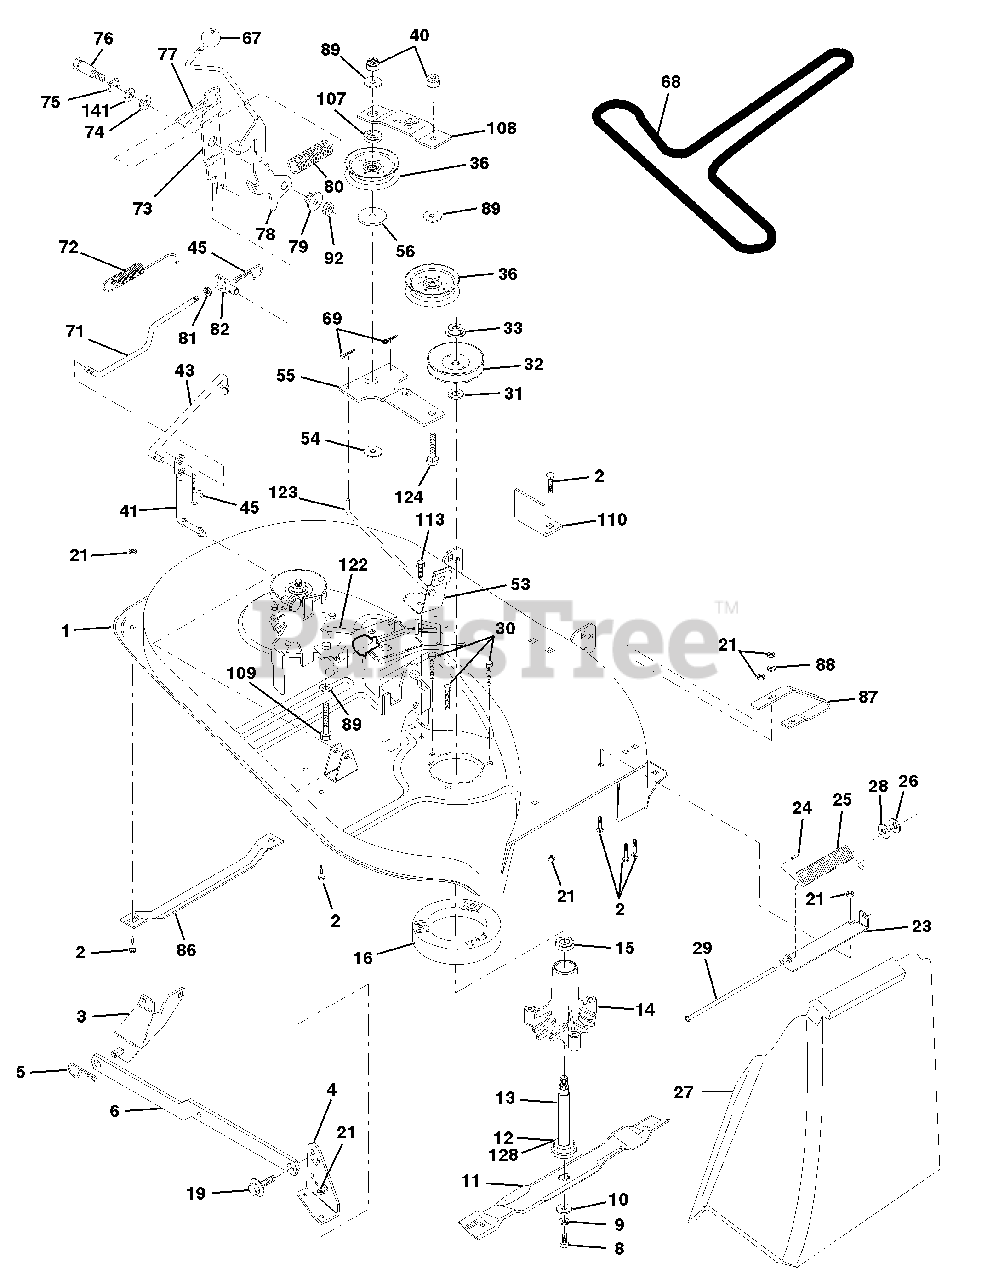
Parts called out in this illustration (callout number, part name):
1	Mower Housing
2	Bolt Rdhd Sqnk 5/16-18unc X3/4
3	Bracket assembly, front
4	Bracket assembly, decl
5	Retaining spring
6	Arm, suspension rear
8	Bolt 3/8-24x1 25 Gr8 Patched
9	Washer Lock Hvy 3/8 Unplated
10	Washer Hard Blade Mower Vented
11	Blade High Lift 38"
12	Bearing Ball #6204 (Mandrel)
13	Shaft Asm W/lower Bearing
14	Housing Mandrel Vented (machd)
15	Bearing Ball Mandrel
16	Stripper MWR
19	Bolt Shoulder
21	Nut Crownlock 5/16-18 UNC
23	Bracket Deflector Mower
24	Cap Sleeve 80 x 112 Blk Mower
25	Spring Deflector
26	Nut Push Phos & Oil
27	Shield Deflector Mower 38" blk
28	Washer 11/32 X 5/8 X 16 Ga
29	Rod Hinge Brt/blk Zinc 9 88 Lg
30	Screw Thdrol Washer Head
31	Washer Spacer Mower Vented
32	Pulley Mandrel 38" Single
33	Nut 9/16 top Lock Flng Cntr
36	Pulley Idler Flat 3060
40	Nut Crownlock 3/8-16 Unc
41	Rod Pivot W/nibs
43	Rod Clutch Secondary W/nibs
45	Spring Retainer 1" Zinc/cad
53	Brake Asm Mower Vented
54	Washer Hardened
55	Arm Idler 38"
56	Spacer Retainer Pm Mower
67	Knob Rd 7/16-14 Plstc Thds Blk
68	V-Belt Mower
69	Pin Cotter 3/32 X 3/4 Cad
71	Rod Clutch Primary 38/42
72	Spring Return
73	Arm Clutch Secondary
74	Washer 25/32 X 1-5/8 X 16 Ga
75	Ring Klip #t5304-75
76	Bolt Shoulder 3/8-16 Unc 1 44
77	Keeper Spring 4000
78	Arm Asm Clutch Primary
79	Bushing 747 Od X 794 Lg Brass
80	Spring Clutch Mower
81	Nut Hex Jam 3/8-16
82	Trunnion Adj '94
86	Runner Mower LH 10 00
87	Runner RH 38"
88	Washer 11/32 X 3/4 X 16 Ga
89	Washer 13/32 X 1 X 12 Ga
92	Nut Lock Hex w/Ins 3/8-16 Unc
107	Spacer Arm Idler Upper Hdn 42"
108	Stiffener Arm Idler Upper 42"
109	Bolt Hex Fin 3/8-16 UNC x 2-1/2
110	Upstop Deck front
113	Screw Thdrol 5/16-18 X 3/4 TYT
122	Rod Brake Mandrel LH 4 856
123	Rod Brake Mandrel RH 10 744
124	Bolt Rdhd 3/8-16uncx1-3/4 Gr5
128	Washer Felt
141	Washer Thrust .75 x 1.230
